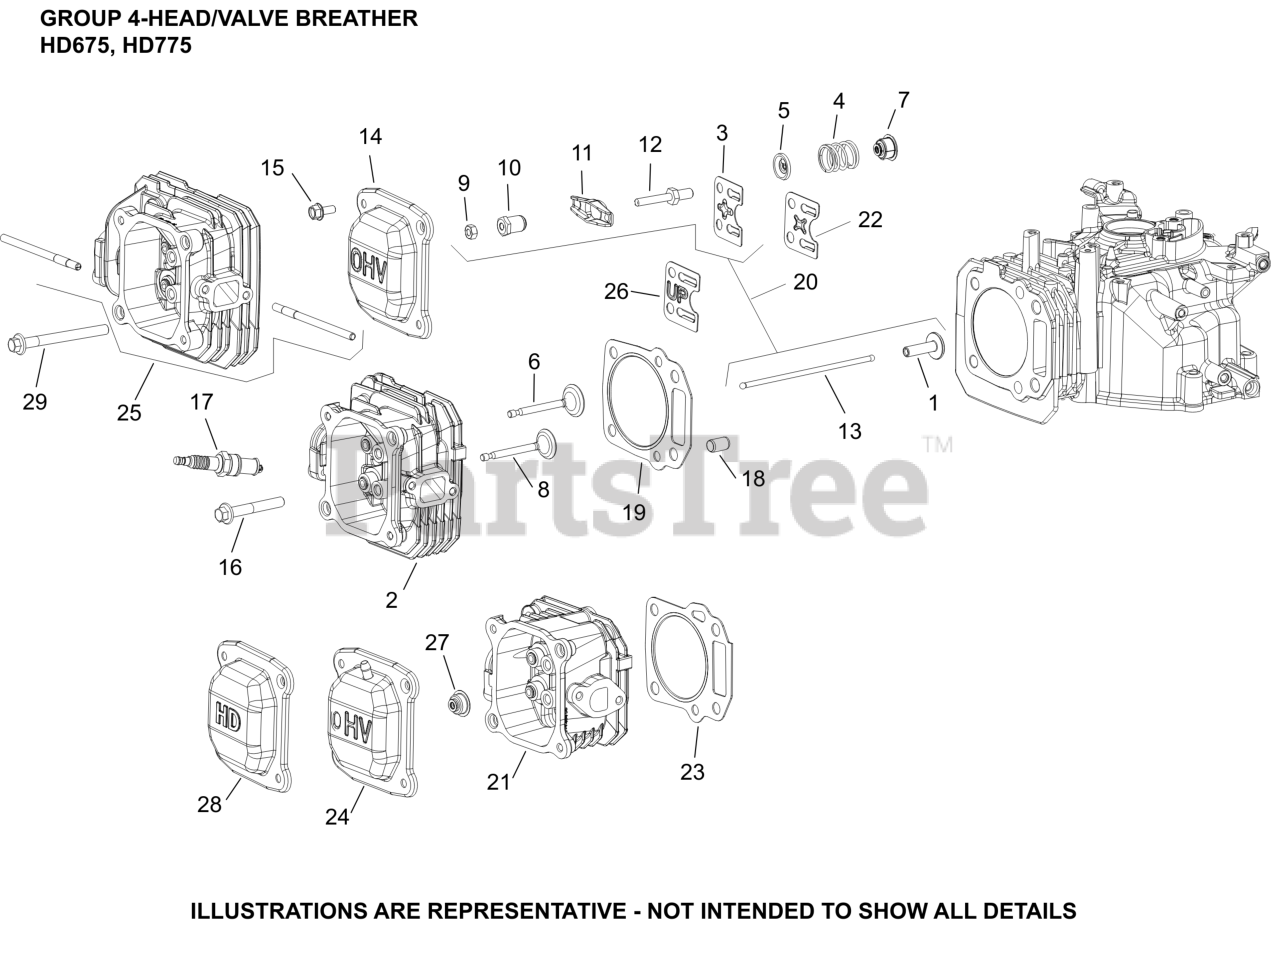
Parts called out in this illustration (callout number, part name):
1	LIFTER, VALVE
2	HEAD, CYLINDER
3	PLATE, PUSHROD GUIDE
4	SPRING, VALVE
5	RETAINER, VALVE SPRING
6	VALVE, INTAKE
7	SEAL, VALVE STEM
8	VALVE, EXHAUST
9	NUT, HEX JAM
10	PIVOT, ROCKER ARM
11	ARM, ROCKER
12	STUD, ROCKER ARM
13	ROD, PUSH-(#1741108S)
14	COVER, VALVE
16	SCREW, HEX FLANGE M8
17	PLUG, SPARK 12MM RFI
18	DOWEL, CYLINDER HEAD
19	KIT, HEAD GASKET-USE 14 841 34-S (XT)
20	KIT, VALVE TRAIN
